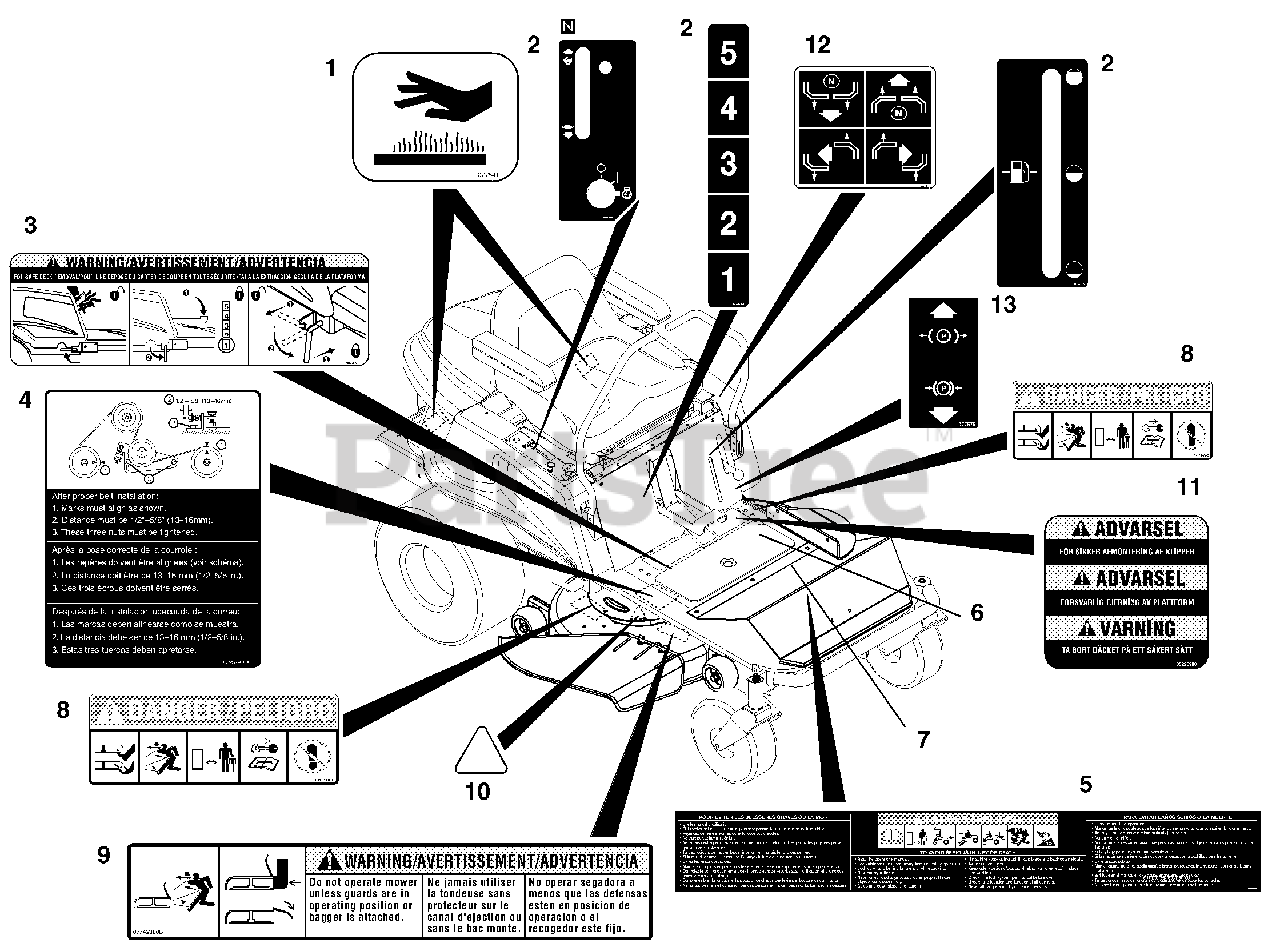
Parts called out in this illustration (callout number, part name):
1	DECAL, HOT SURFACE
2	DECAL, INSTRUCTIONAL SET
3	DECAL, SAFE DECK REMOVAL
4	DECAL-BELT DIAGRAM 42"
5	DECAL, BILINGUAL DANGER
6	NON-SKID COVER
7	NONSKID COVER
8	DECAL, MOWER PAN DANGER
9	DECAL, WARNING
10	DECAL, BLADE ALIGNMENT
11	DECAL, SAFE DECK REMOVAL, EXP.
12	DECAL, INSTRUCTIONAL-STEERING
13	DECAL, PARKING BRAKE LEVER
